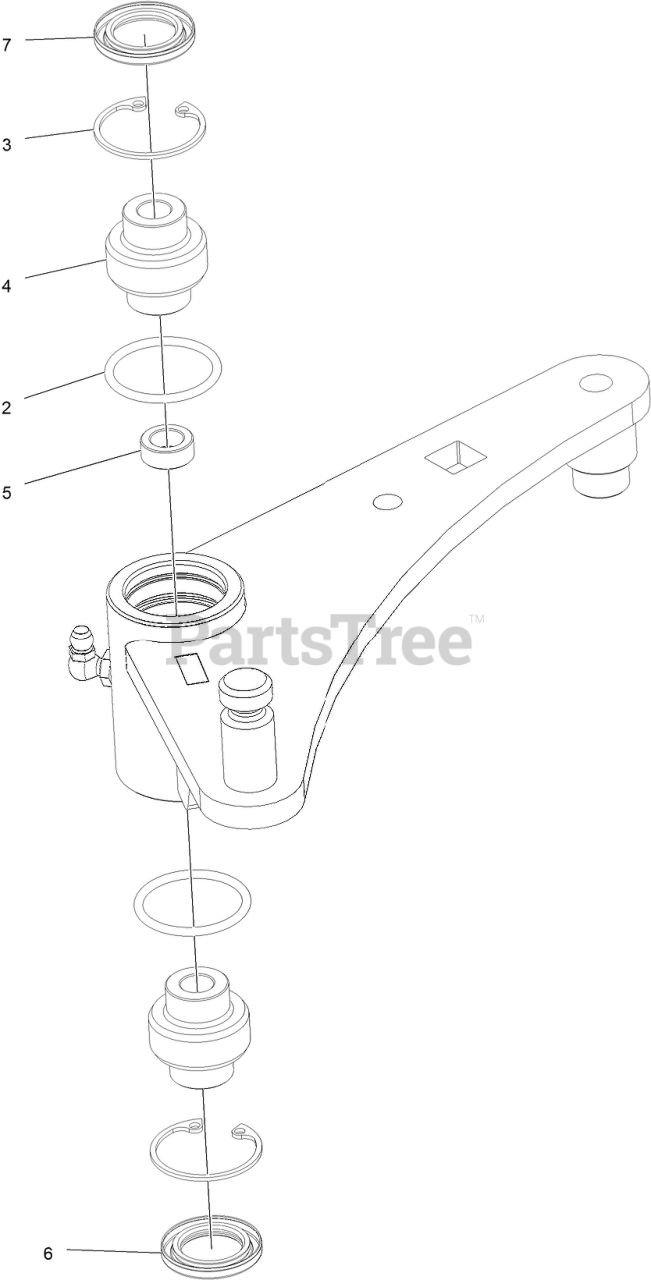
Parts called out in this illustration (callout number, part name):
3	RING-SNAP
4	BEARING-SPHERICAL
6	SEAL-LIP, DOUBLE
7	SEAL-LIP, SINGLE
